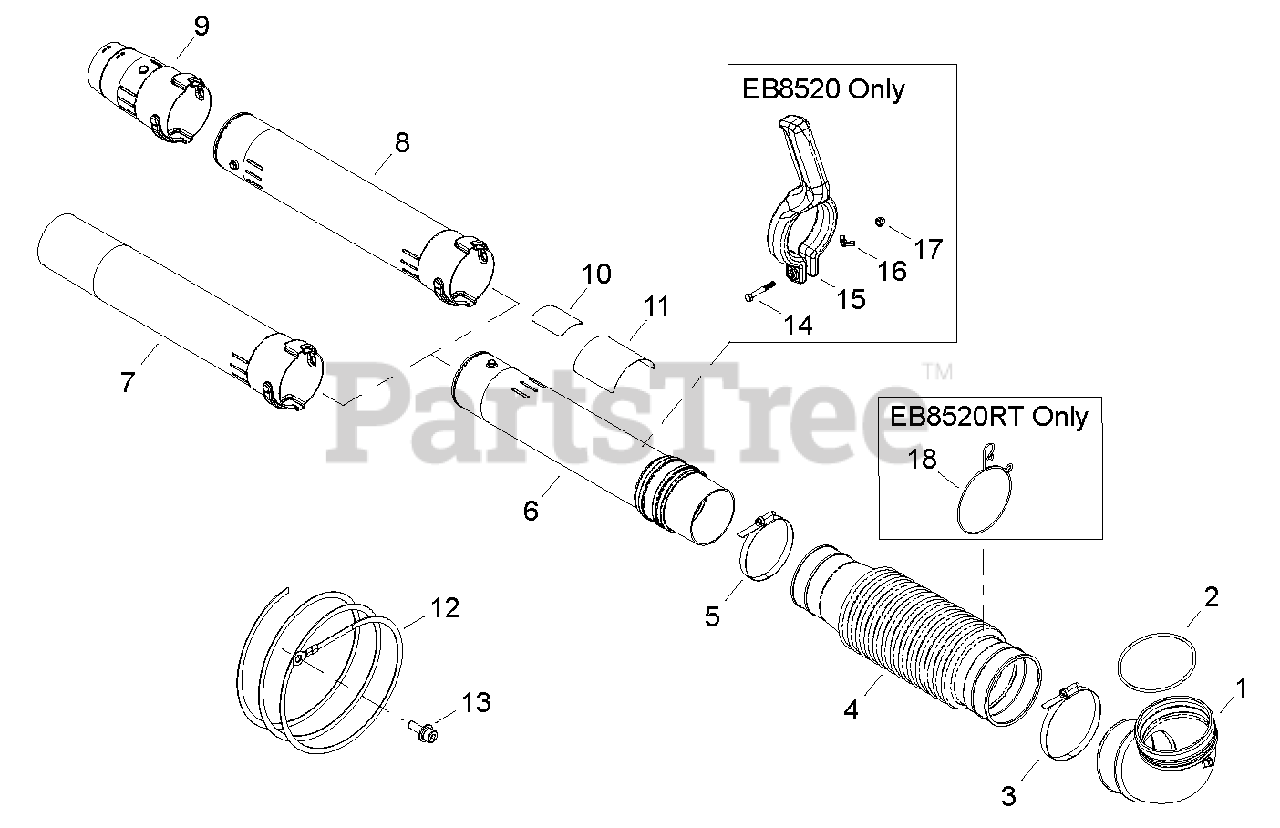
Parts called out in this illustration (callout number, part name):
1	TUBE, BLOWER - ELBOW
2	O-RING
3	CLAMP
4	FLEXIBLE TUBE
5	CLAMP
6	TUBE, BLOWER - SWIVEL
7	NOZZLE - 74mm
8	TUBE, EXTENSION
9	NOZZLE - 65mm
10	LABEL - CAUTION
11	LABEL - C4
12	LEAD - ANTI-STATIC
13	SCREW - 5X16
14	SCREW - 6X60
15	HANDLE
16	WINGNUT
17	NUT - 6
